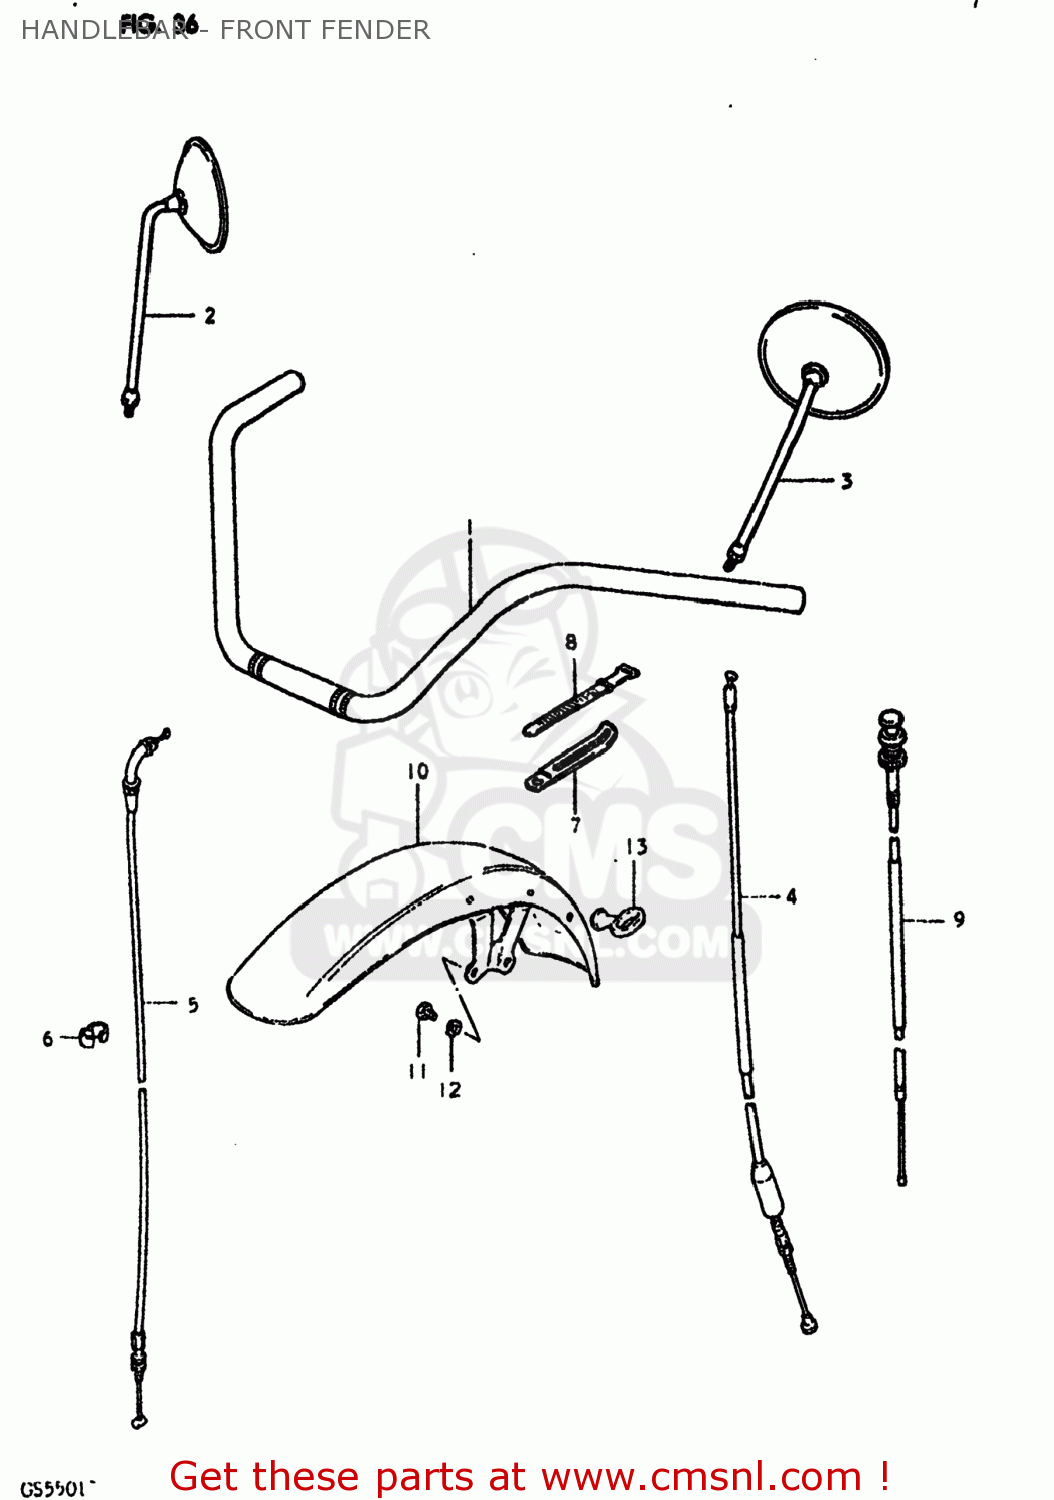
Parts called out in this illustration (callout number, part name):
1	HANDLEBAR
2	MIRROR ASSEMBLY,REAR VIEW
3	MIRROR ASSEMBLY,LEFT
4	CABLE ASSY,CLUTCH
5	CABLE ASSEMBLY,THROTTLE
6	CLIP
7	CLAMP
8	CLAMP
9	CABLE ASSEMBLY,STARTER
10	FENDER,FRONT
11	BOLT
12	LOCK WASHER
13	GUIDE,CABLE
